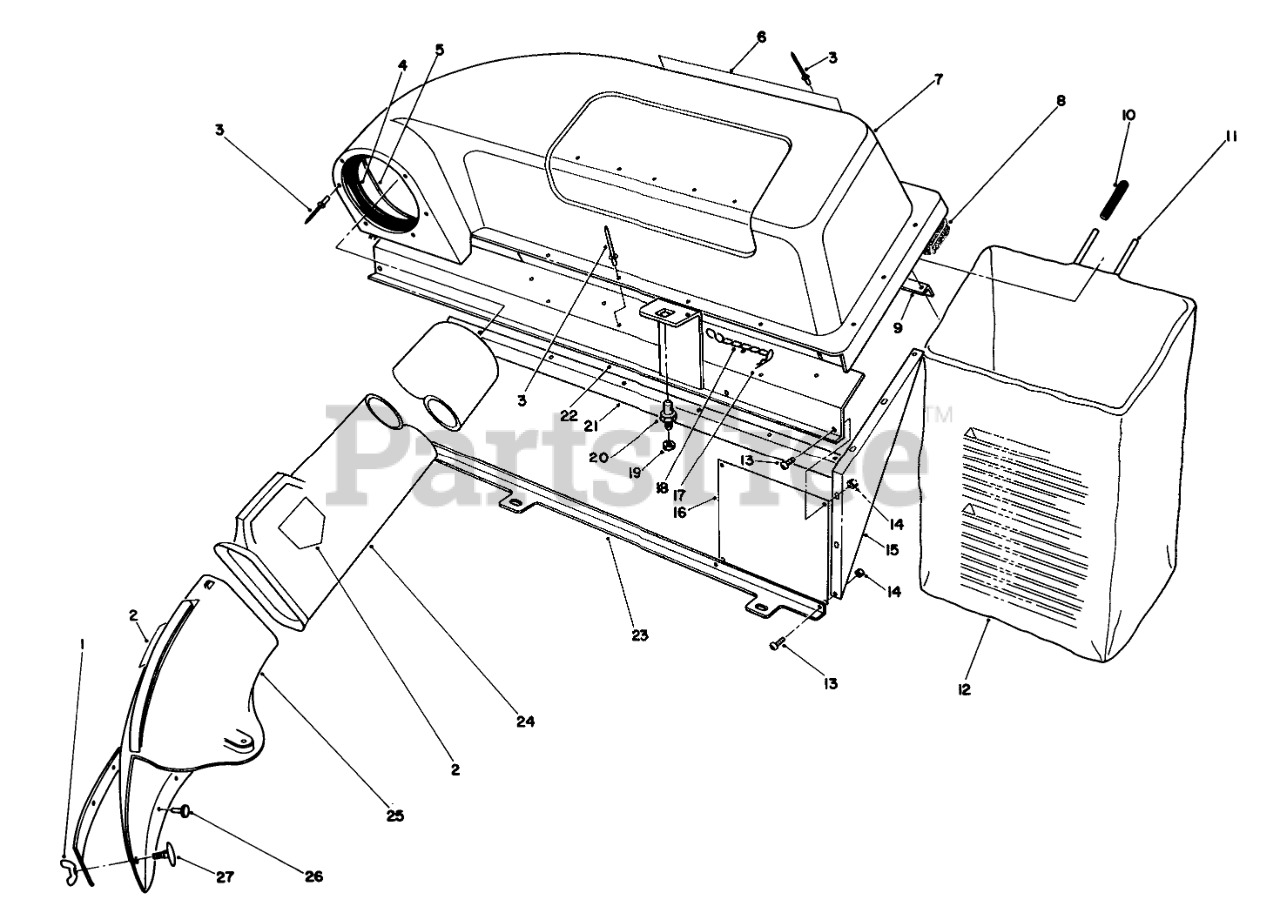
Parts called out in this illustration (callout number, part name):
1	NUT-WING
2	DECAL-DANGER
3	RIVET-POP
4	EXH DUCT GASKET
5	Ring-Gasket
6	Decal-Twin Bagger
7	Cover
8	FOAM SEAL
9	BAG FRAME BRKT
10	GRIP-HANDLE, BAG
11	BAG FRAME
13	SCREW-PPH
14	NUT-LOCK, NI
15	Plate-Side
16	Shield-Muffler
17	HAIRPIN COTTER
18	6-LINK CHAIN W/HOOK
19	NUT-LOCK, NI
20	Pin-Mounting
21	BAG SUPPORT CHANNEL
22	Baffle
23	Bracket-Base
24	Duct Assembly (Incl. Ref. #2)
25	Chute Assembly (Incl. Ref. #2 & 25)
26	RIVET 3/16 X 7/16
27	STEP BOLT
